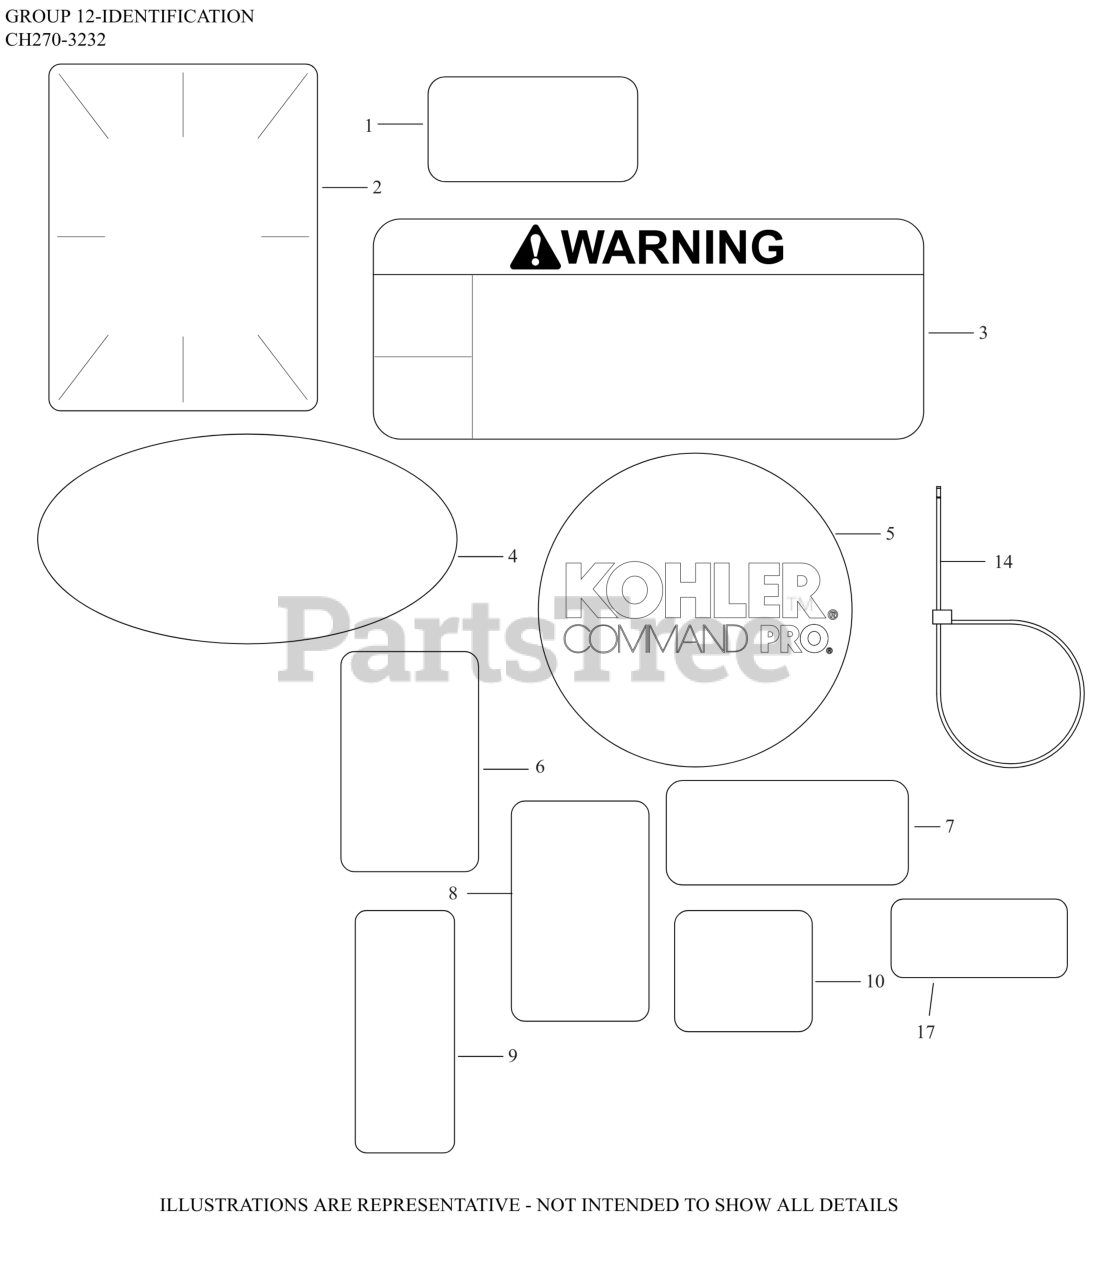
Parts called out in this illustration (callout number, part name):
1	LABEL, MAINTENANCE (CKY)
2	LABEL, CLEAR LAMINATION
3	DECAL, WARNING
4	DECAL, QUAD CLEAN SILVER
5	LABEL, RECOIL 62MM
6	DECAL, SNOW FLAKE
7	LABEL, CANADIAN COMPLIANCE
8	DECAL, SUN
9	DECAL, FUEL/CHOKE - ON/OFF
10	DECAL, BASE ARROW
17	DECAL, ETHANOL WARNING
